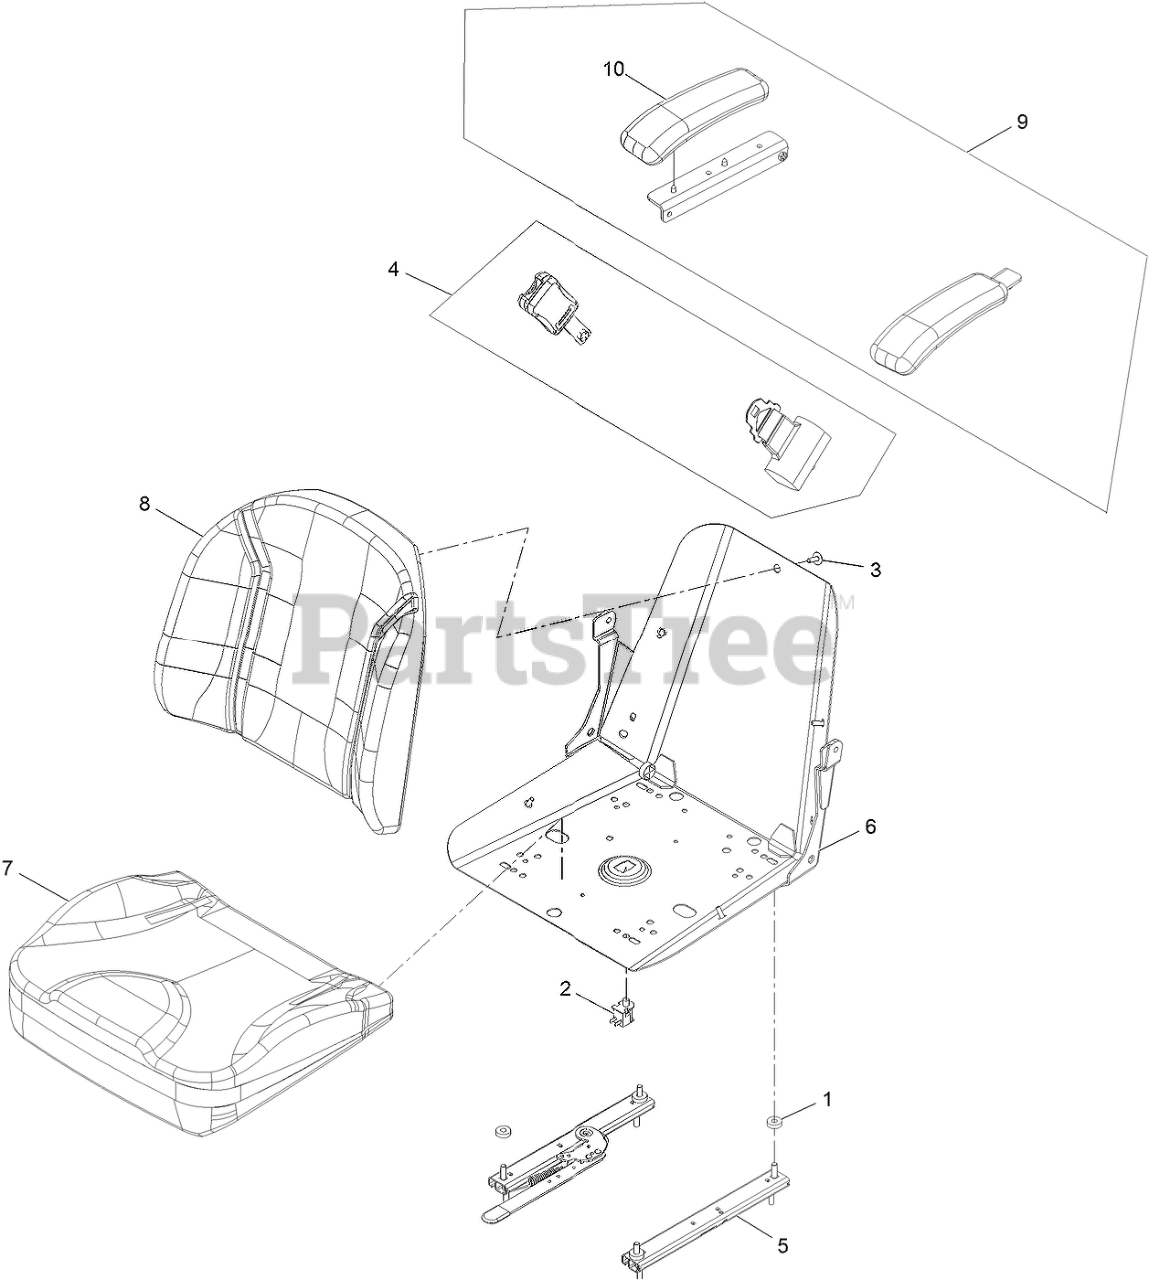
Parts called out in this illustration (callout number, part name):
2	SWITCH-BAIL
3	BOLT-SEAT
4	KIT-SEAT BELT
5	ASM-SEAT TRACK SVC
6	FRAME-SEAT SVC
7	COVER-SEAT BOTTOM SVC
8	CUSHION-SEAT, BACK
9	ARMREST KIT
10	CUSHION-REST, ARM
